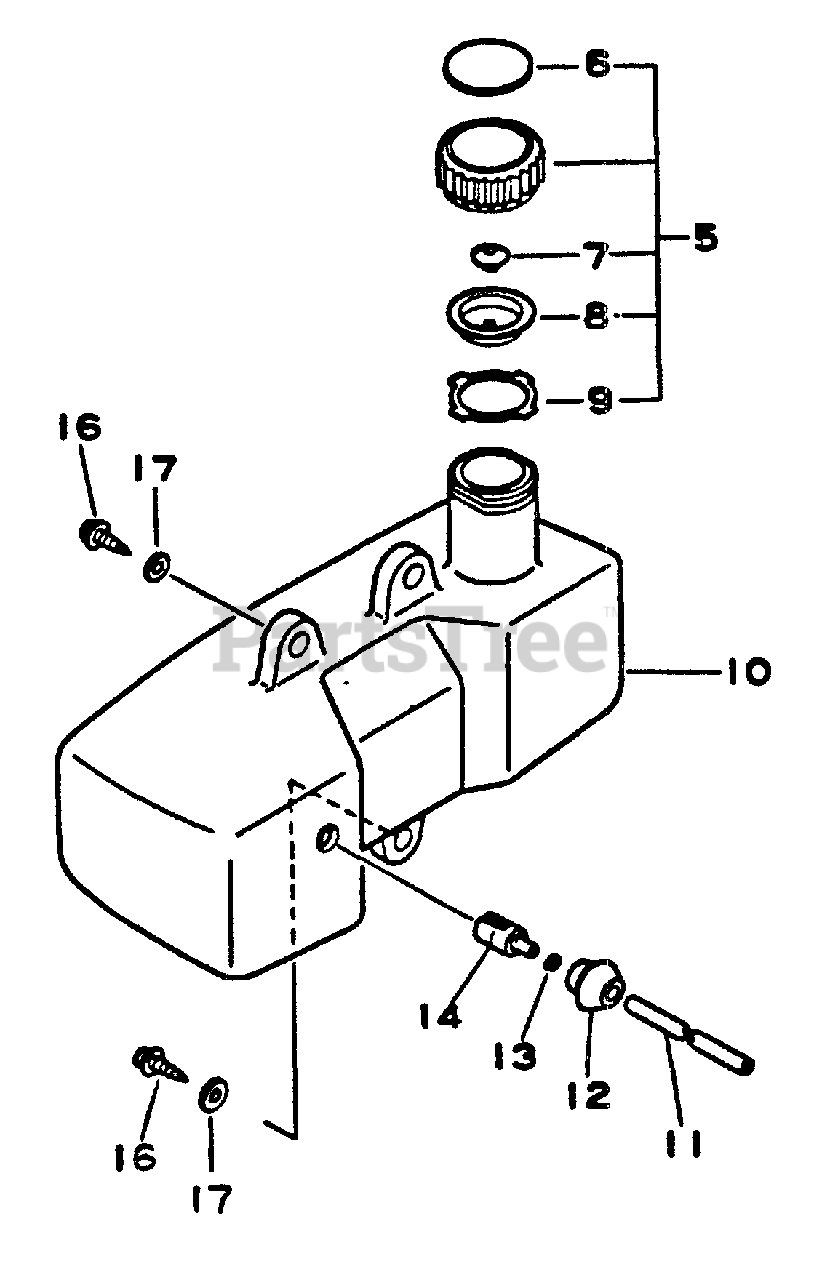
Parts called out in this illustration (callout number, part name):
5	CAP ASSY
6	LABEL - FUEL MIX
7	VALVE, CHECK
8	HOLDER, VENT
9	GASKET, CAP
10	TANK, FUEL
11	PIPE, FUEL 3×5×210 BLACK
13	CLIP 6 MM
14	FILTER, FUEL
16	SCREW 5×14
17	WASHER 5.5×12×0.8
18	BRACKET, SWITCH
19	SWITCH, ON-OFF
